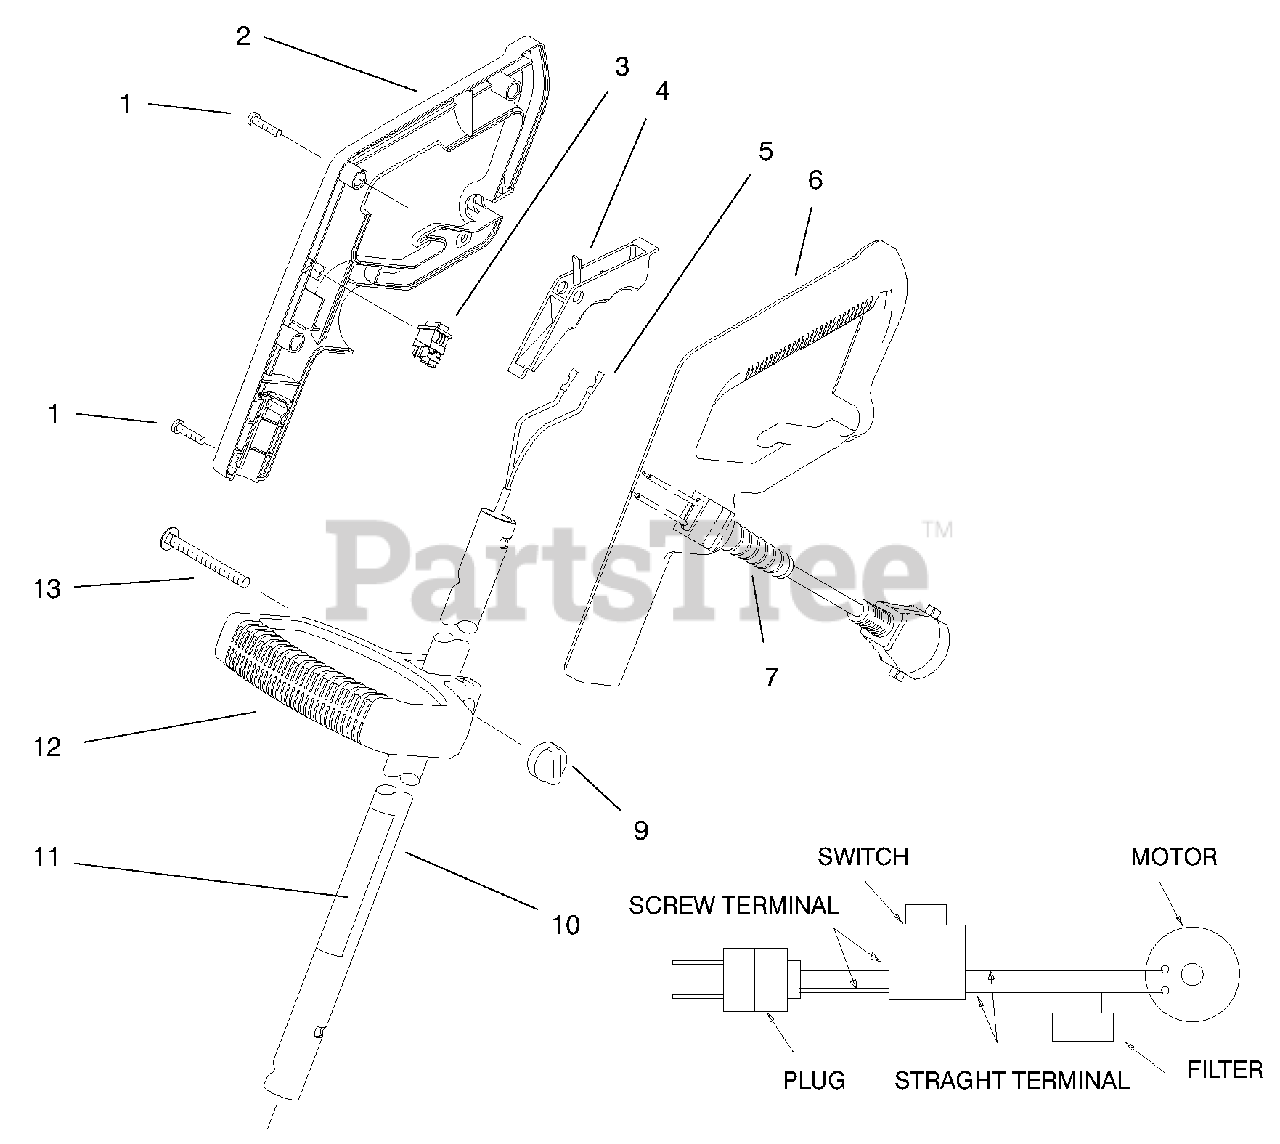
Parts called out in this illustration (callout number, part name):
1	Screw-Pan Hd.
2	Grip-Hand R.H.
5	Harness-Wire
6	Grip-Hand L.H.
7	Cord-Power
10	Tube Assembly (Incl. Ref. #11)
11	Decal-Safety
12	Handle-Mid
13	Screw-Carriage
